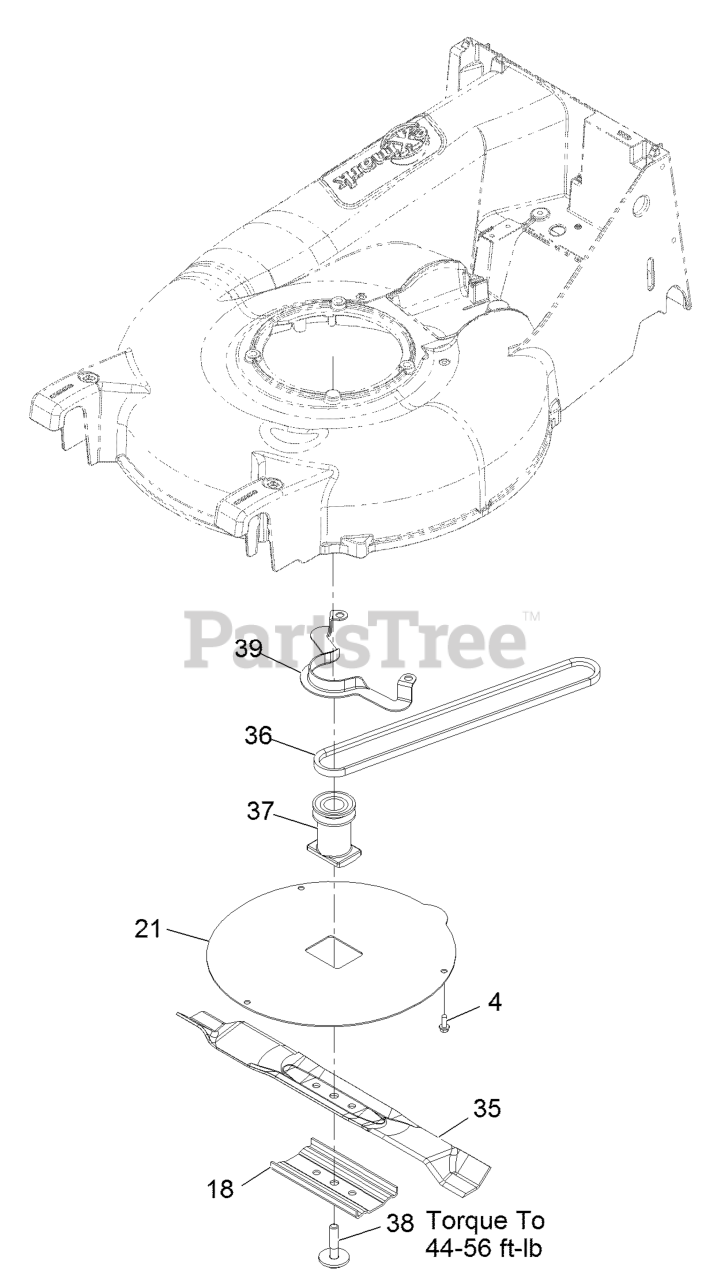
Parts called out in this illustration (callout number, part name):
4	SCREW-HWH
18	SUPPORT-BLADE
36	BELT,3L P21 DRIVE
37	BLADE-ADAPTER
38	BOLT-BLADE, SEM
39	GUIDE-BELT
